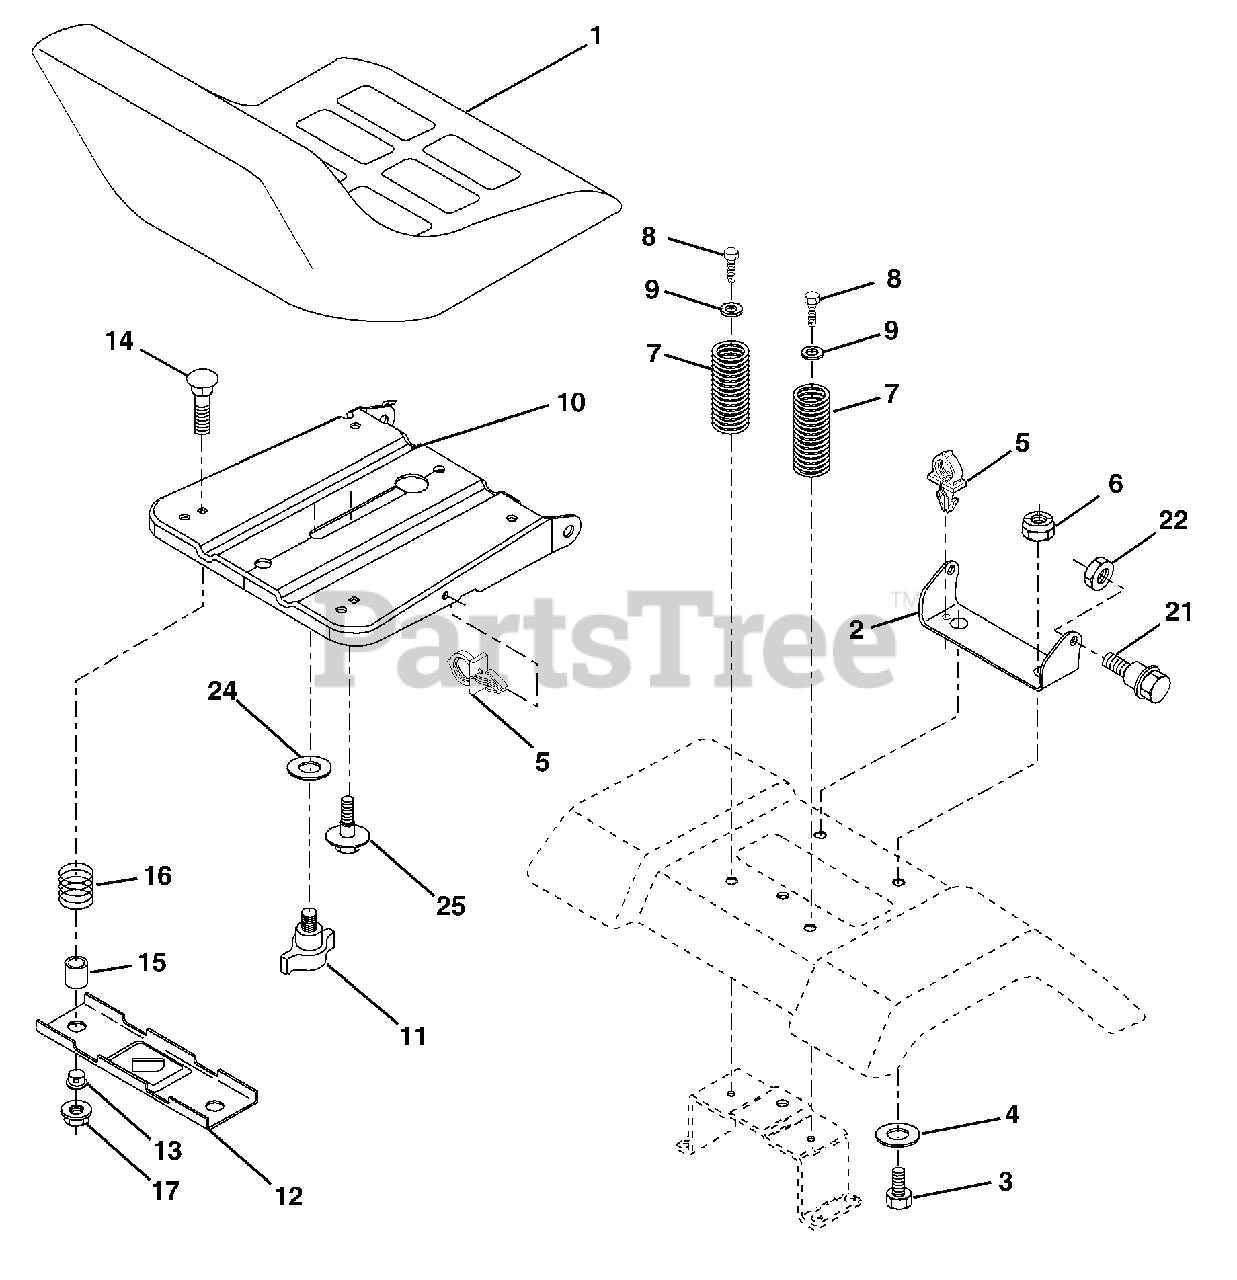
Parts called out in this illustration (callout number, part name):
1	Seat
2	Bracket Pivot Seat
3	Bolt Fin Hex 3/8-16 Unc x 1
4	Washer 13/32 x 3/4 x 10 Ga
5	Clip Push In Hinged
6	Nut Hex Lock w/Ins 3/8-16 Unc
7	Spring Seat Cprsn 2 250 Blk Zi
8	Screw 3/8-16 x 1
9	Washer 13/32 x 1 x 14 Ga
10	Pan Seat
11	Knob Seat Adj Wingnut
12	Bracket Pnt Mounting Switch
13	Bushing Snap Blk Nyl 50 Id
14	Bolt Rdhd Sht Nk 1/4-20 x 1-1/2
15	Spacer Split 28 x 96 Zinc
16	Spring Cprsn 1 27 Blk Pnt
17	Nut Lock 1/4 Lge Flg Gr 5 Zinc
21	Bolt Shoulder 5/16-18 Unc-2A
22	Nut Hex Lock w/Ins 5/16-18
24	Washer 17/32 x 1-3/16 x12 Ga.
25	Bolt Shoulder
